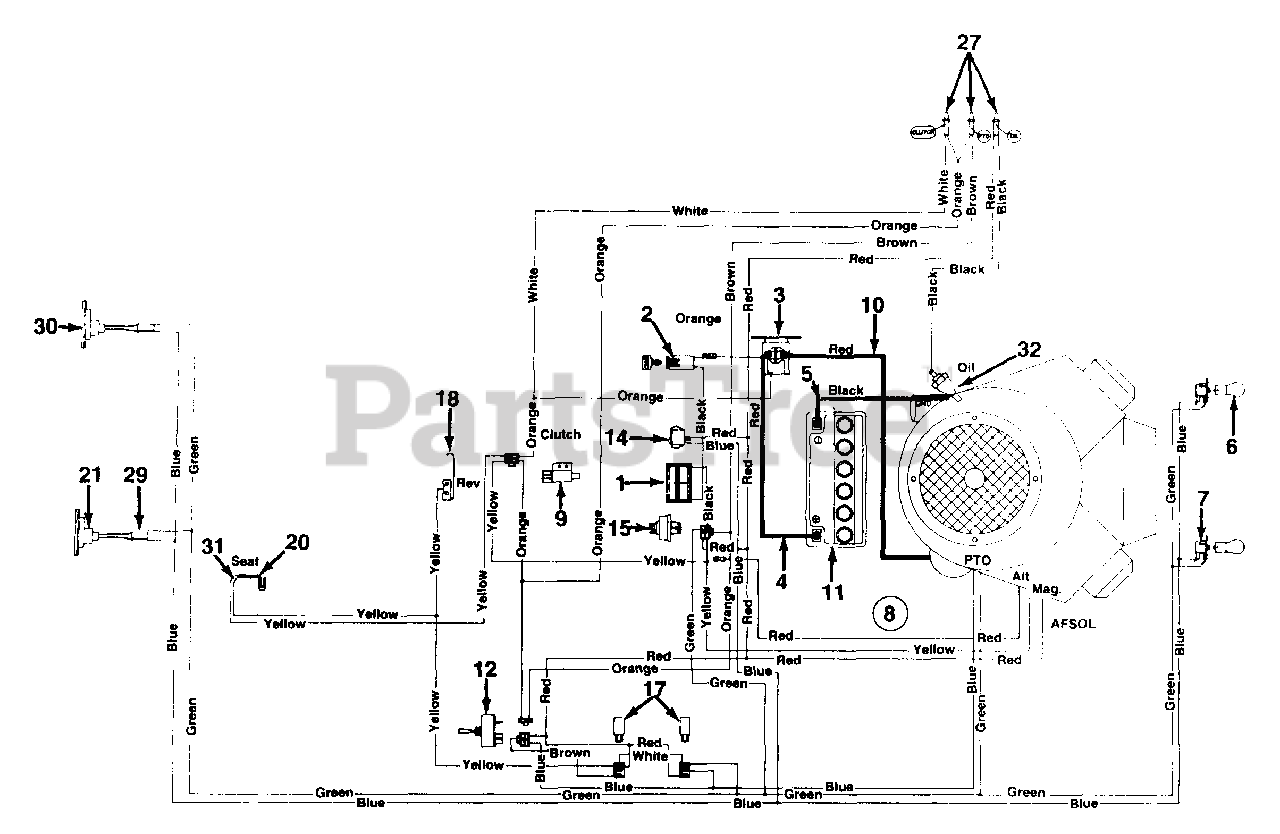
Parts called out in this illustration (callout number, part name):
1	Ammeter
2	Fuse 20 Amps
3	Solenoid
4	Wire
5	8 Ga. Black Wire 12" Lg.
6	Bulb
7	Socket
8	Wire Harness
9	Safety Switch (Clutch)
10	6 Ga. Red Wire 20" Lg.
11	Battery (275 Cold Crank Amps)
12	Switch (PTO)
14	Light Switch
15	Ignition Switch
17	Relay
18	Spring Lever (Reverse)
20	Safety Switch (Seat)
21	Taillight
27	Bulb
29	Taillight Harness
30	Bulb
31	Safety Switch (Seat)
32	Oil Pressure Switch
